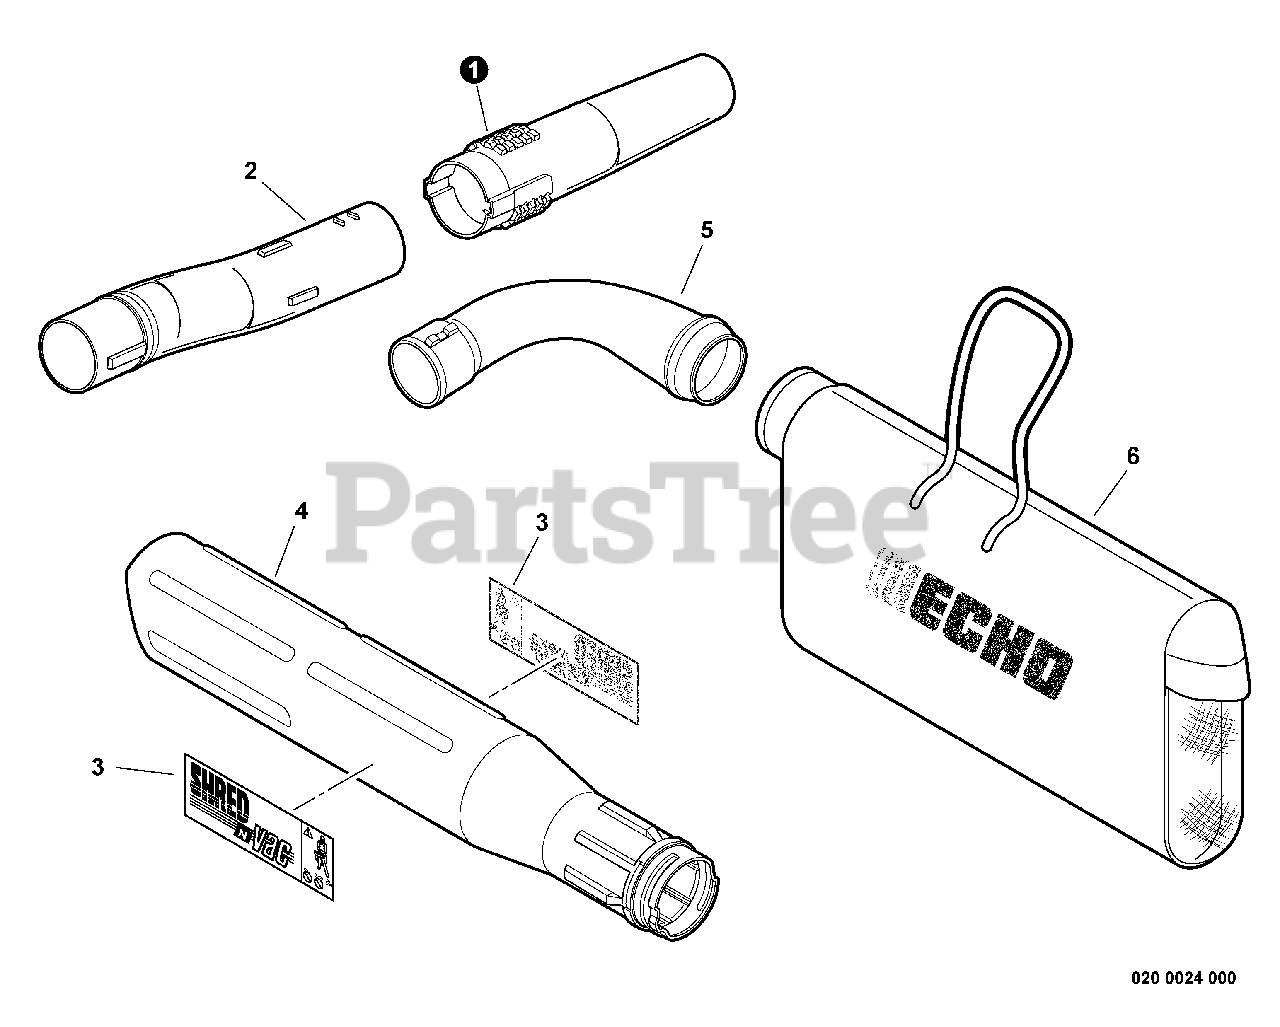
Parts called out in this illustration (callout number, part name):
1	TUBE, BLOWER - STRAIGHT NOZZLE
2	TUBE, BLOWER - CURVED
3	LABEL - SHRED 'N' VAC
4	TUBE, VACUUM
5	TUBE, BLOWER - ELBOW
6	BAG, DEBRIS
